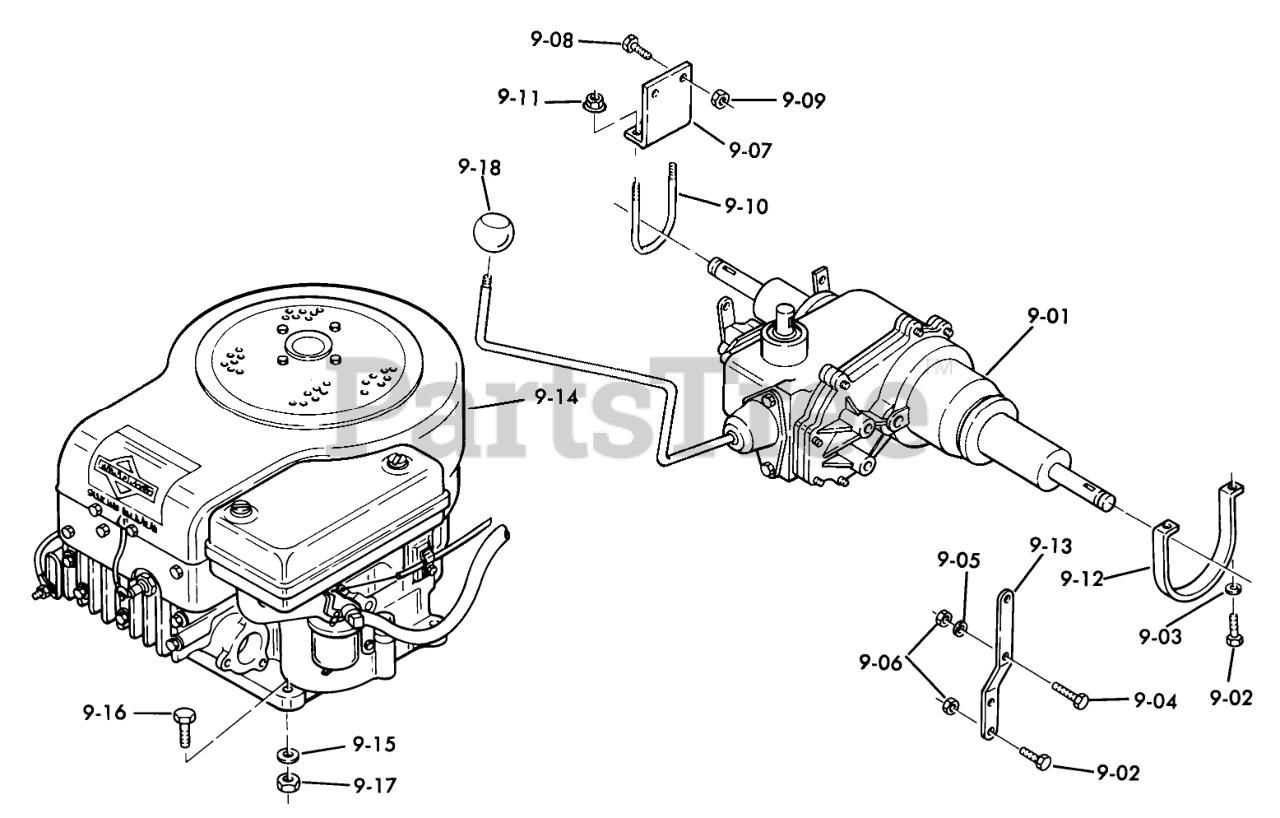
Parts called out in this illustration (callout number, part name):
9-01	Ass-y. Transmission
9-02	Bolt
9-03	Lockwasher
9-04	Bolt
9-05	WASHER 5/16 SAE
9-06	Nut
9-07	Bracket-Trans. Mtg.
9-08	Bolt
9-09	Nut
9-10	"U" Bolt Axle Mount
9-11	LOCKNUT-FLANGE
9-12	Girth-Transmission
9-13	Bar-Trans Support
9-13	Lockwasher
9-13	Bolt
9-13	WASHER 5/16 SAE
9-13	Nut
9-14	Engine-8 HP Briggs
9-14	Engine-10 HP Briggs
9-15	WASHER 5/16 SAE
9-16	Bolt
9-17	Nut
9-18	SHIFT KNOB
